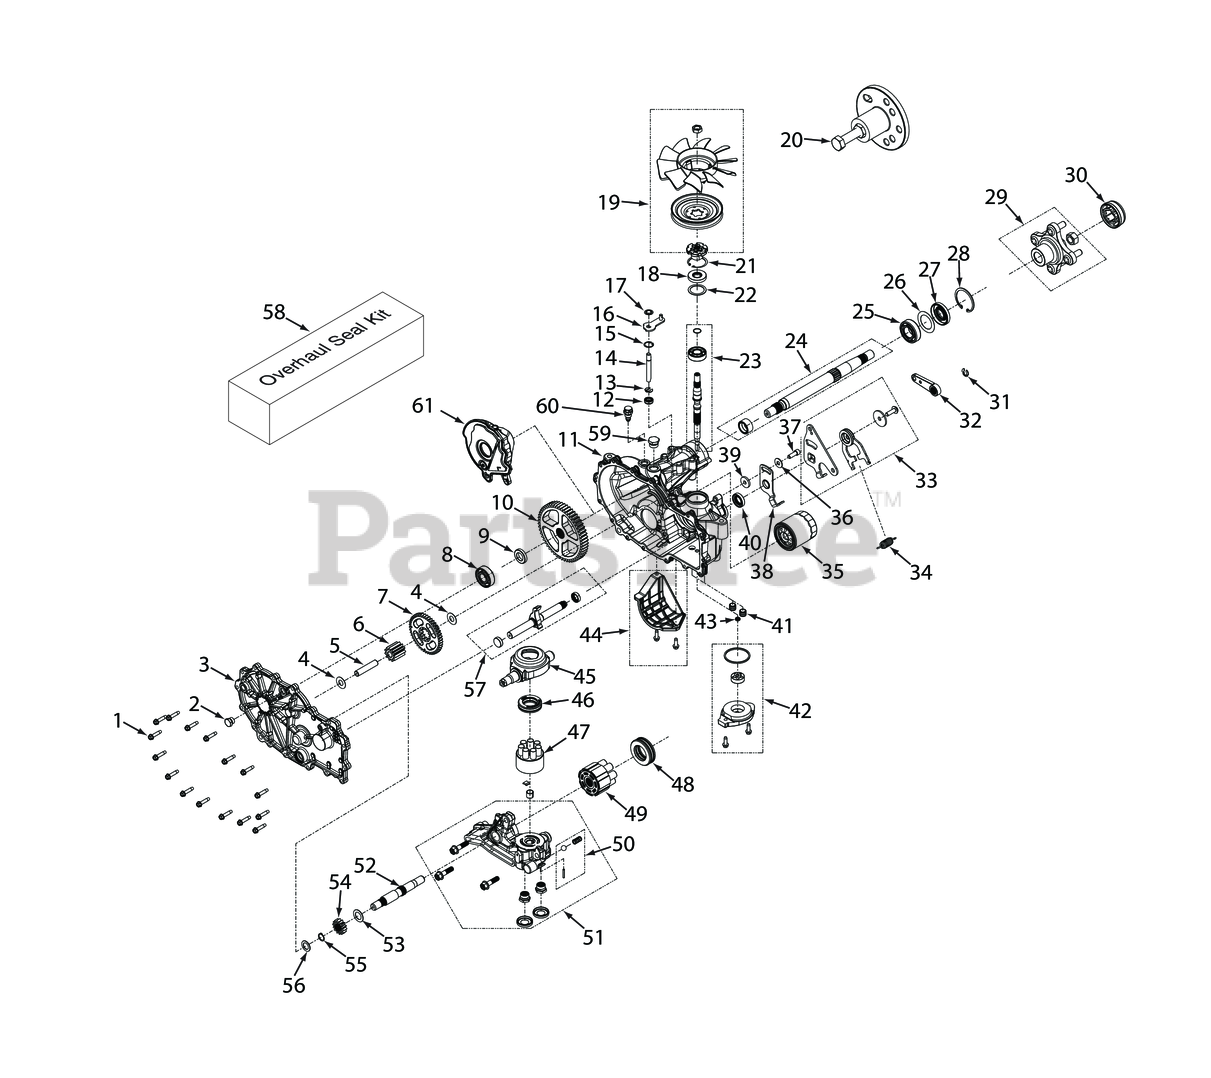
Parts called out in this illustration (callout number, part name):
1	Bolt, Hex Head 1/4-20 x 1-1/8"
2	Plug, External Hex Vent 9/16-18
3	Kit, Side Cover LH
3	Kit, Side Cover RH
4	Washer, .5 x 1.0 x .03
5	Jackshaft Pin
6	Gear, 11T
7	Gear, 45T
8	Kit, Bearing
9	Spacer, .750 x 1.320 x .257
10	Gear, 54T
11	Kit, Main Housing LH, Charge, Control
11	Kit, Main Housing RH Charge, Control
12	Seal, Lip, .375 x .75 x .25
13	Ring, .Retaining .375 External
14	Rod, By-Pass
15	R i n g , Retaining .750 Internal
16	Arm, Bypass (LH)
16	Arm, Bypass (RH)
17	Ring, Retainging .375 External
18	Seal, Lip 17 x 40 x 7
19	Kit, Fan/Pulley
20	Kit, Hub Puller
21	R i n g , Retaining 2.06 Internal
22	Washer, 1.23 x 1.56 x .04
23	Kit, Input Shaft
24	Kit, Shaft, Axle
25	Bearing, Ball 1.0 x 52 x 15 Open
26	Spacer, 1.355 x 2.035 x .021
27	Seal, Lip TC4 1.0 x 2.06 x .38
28	R i n g , Retaining 2.06 Internal
29	Hub, 4-Bolt
30	Cap, Axle
31	Ring, Retaining External .375"
32	Handle, Brake
33	Kit, RTN Bi-Directional (Right Side)
33	Kit, RTN Bi-Directional (Left Side)
34	Spring, Extension, RTN - 44lbs
35	Filter, Oil
36	Washer, 7/16 x 7/8 OD x .06 HT
37	Bolt, Hex Head Cap Screw 5/16-24 x 1" Patch
38	Arm, Neutral (Left Side)
38	Arm, Neutral (Right Side)
39	Spacer, .32 ID x 1.005 OD x .1495 Thk
40	Seal, Lip 18 x 32 x 7
41	Tube, Charge Triple O-ring
42	Kit, Charge Pump
43	Kit, Gerotor Seal
44	Kit, Filter Guard (LH)
44	Kit, Filter Guard (RH)
45	Trunnion, Swashplate
46	Ball Thrust Bearing
47	Kit, Cylinder Block
48	Thrust Ball Bearing Assembly
49	Kit, 16cc Cylinder Block Assembly (steam
50	Kit, Charge Relief
51	Kit, Charge Relief
51	Kit, Center Section, LH Charge
52	Shaft, Motor
53	Washer, .72 x 1.16 x .04
54	Washer, Flat, .71 x 1.16 x .04
55	Ring, Retaining .625
56	Washer, HT .62 ID x 1.0 OD x .05 Thick
57	Kit, Outboard, RH Rot B / LH Rot A (LH)
57	Kit, Outboard, RH Rot A / LH Rot B (RH)
58	Kit, Seal (ZT-2800)
59	Plug, 3/4-16
60	Fitting 9 /16 - 18, Breather
61	Expansion Tank, Internal LH
61	Expansion Tank, Internal RH
